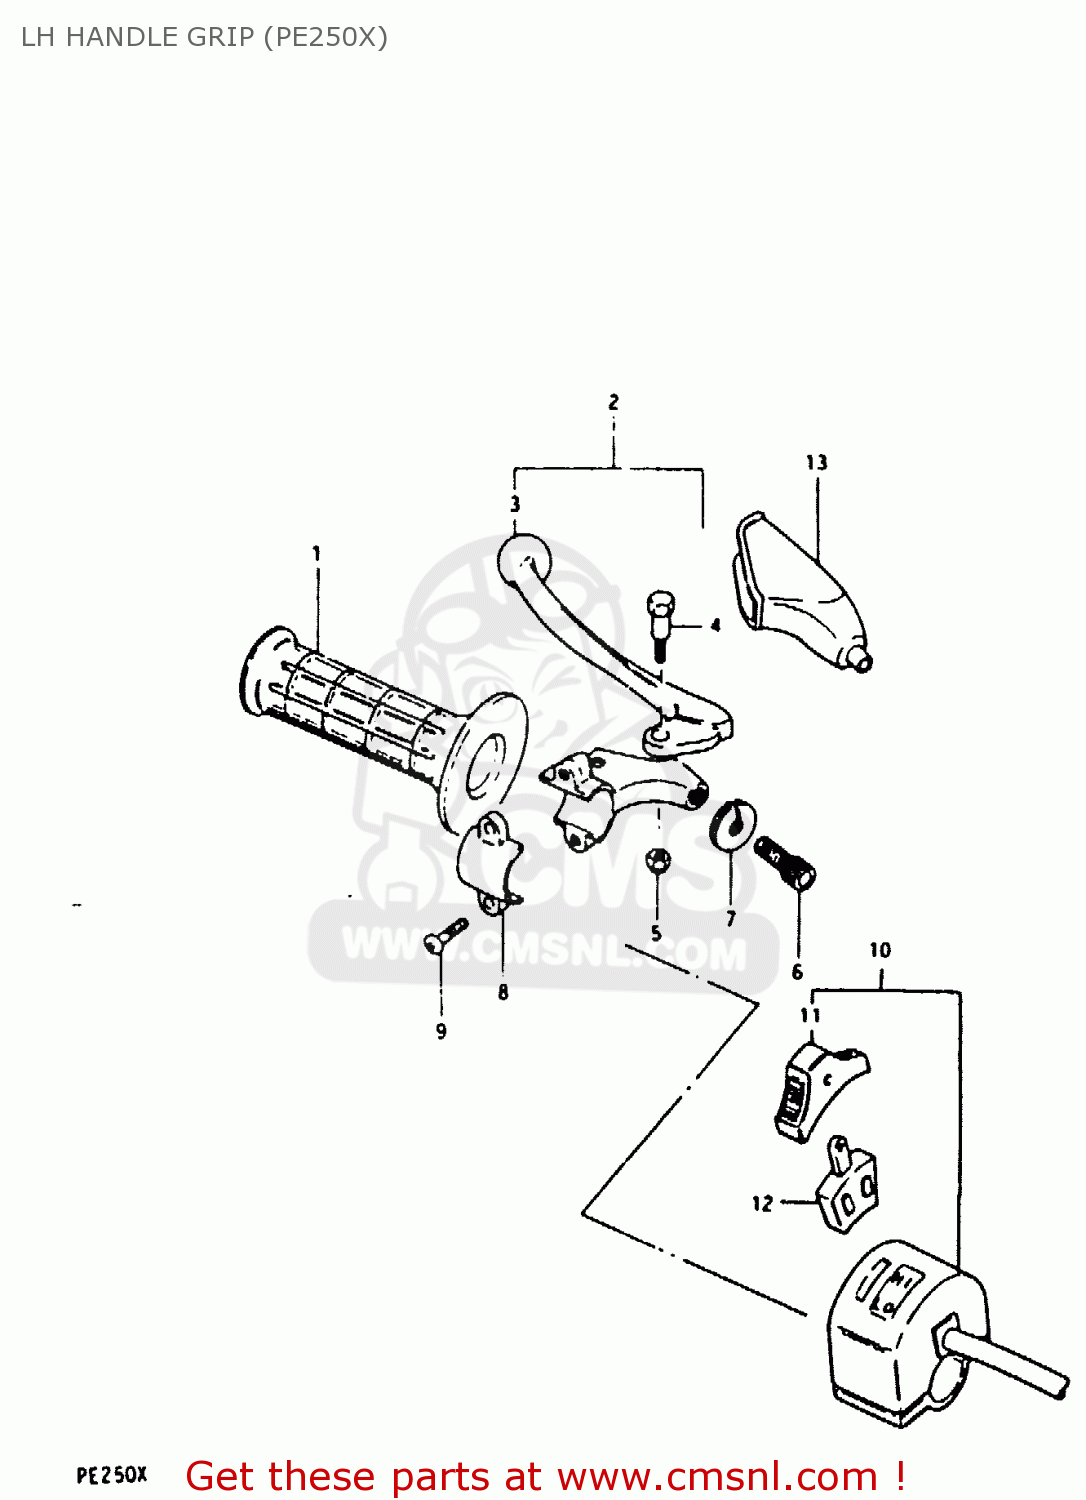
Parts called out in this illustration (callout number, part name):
1	GRIP,LEFT
2	LEVER ASSEMBLY
3	LEVER,CLUTCH
4	BOLT,LEVER
5	NUT 6MM
6	ADJUSTER,CABLE
7	NUT,CABLE ADJUSTER
8	BRACKET,LEVER
9	SCREW
10	SWITCH,DIMMER
11	KNOB,LIGHTING & DIMMER
12	BLOCK,LIGHTING/DIMMER
13	COVER,CLUTCH LEVER
